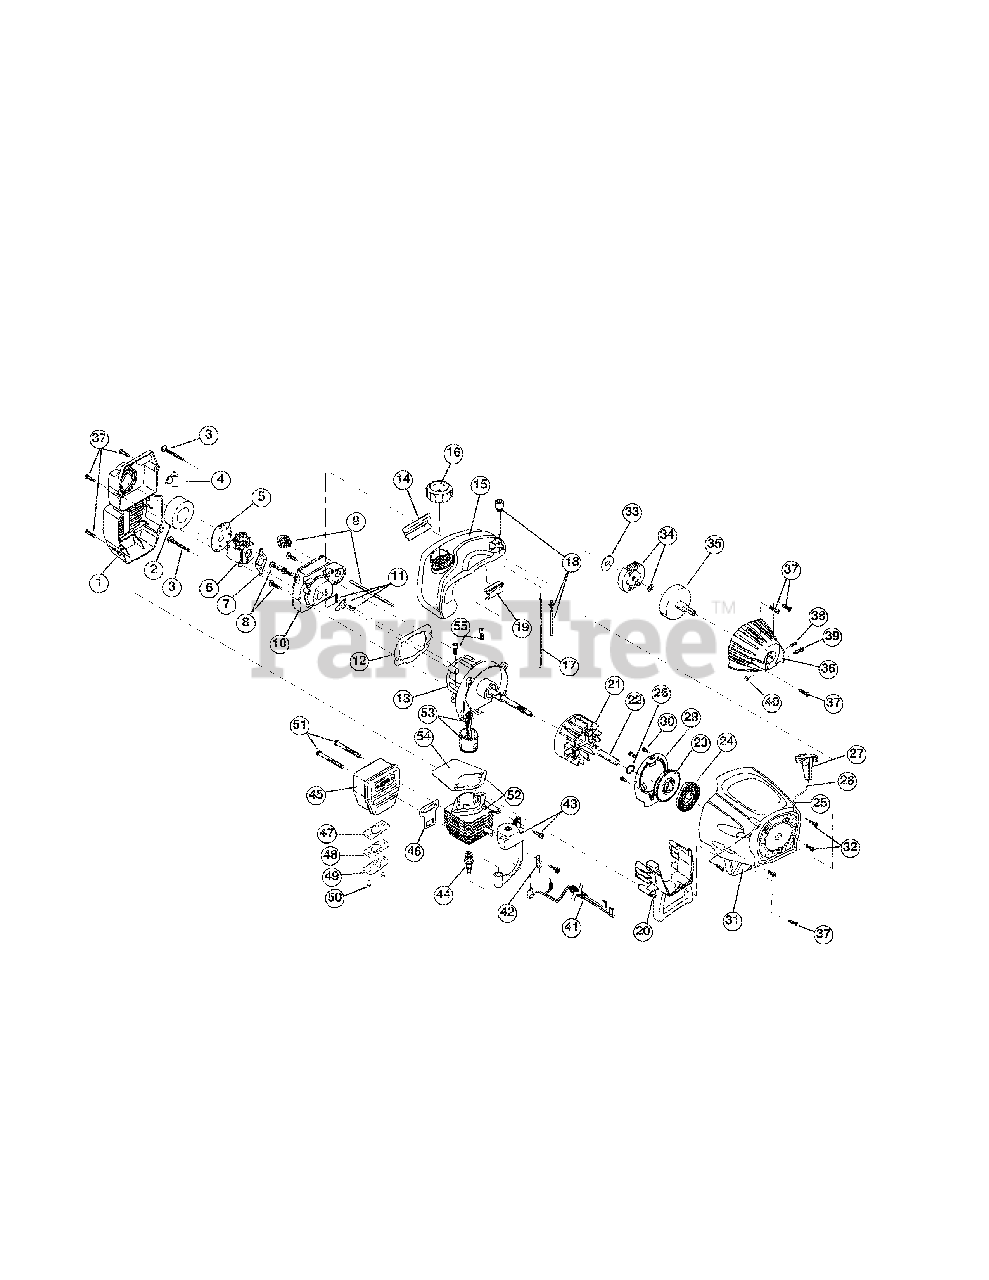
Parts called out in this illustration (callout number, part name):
1	Air Cleaner Cover Assembly (includes 2 & 37)
2	Air Cleaner Filter
3	Carburetor Mounting Screw Assembly
4	Choke Extension
5	Choke Plate
6	Carburetor Assembly (includes 7 & 18)
7	Carburetor Gasket
8	Carb Mount Screw
9	Primer & Hose Assembly
10	Carb Mount Assembly (includes 8, 11 & 12)
11	Reed Assembly
12	Carburetor Mount Gasket
13	Crankcase Service Assembly (includes 8)
14	Rear Mounting Pad
15	Fuel Tank Assembly (includes 16-18)
16	Fuel Cap Assembly
17	Fuel Return Line
18	Fuel Line Assembly
19	Front Mounting Pad
20	Shroud Extension & Stand
21	Flywheel Assembly
23	Recoil Pulley Assembly (includes 24, 26 & 28)
24	Recoil Spring
25	Rope Guide
26	Pulley Retainer
27	Pull Handle
29	Pressure Plate Assembly
30	Plate Screw
31	Starter Housing Assembly (includes 23-30, 32 & 37)
32	Housing Screw
33	Clutch Washer
34	Clutch Rotor Assembly
35	Clutch Drum Assembly
36	Clutch Cover Assembly (includes 37-40)
37	Cover Screw
38	Anti-Rotation Screw
39	Clamping Screw
40	Clamping Nut
41	Wire Leads and Sleeve
42	Ground Tab
43	Module Assembly (includes 42)
45	Muffler Assembly (includes 46-51)
46	Exhaust Gasket
47	Spark Arrestor Screen
48	Exhaust Hood Diverter
49	Exhaust Hood
50	Screws
51	Muffler Mounting Bolts
52	Cylinder Assembly (includes 54 & 55)
53	Piston and Rod Assembly
54	Cylinder Gasket
55	Cylinder Bolt
